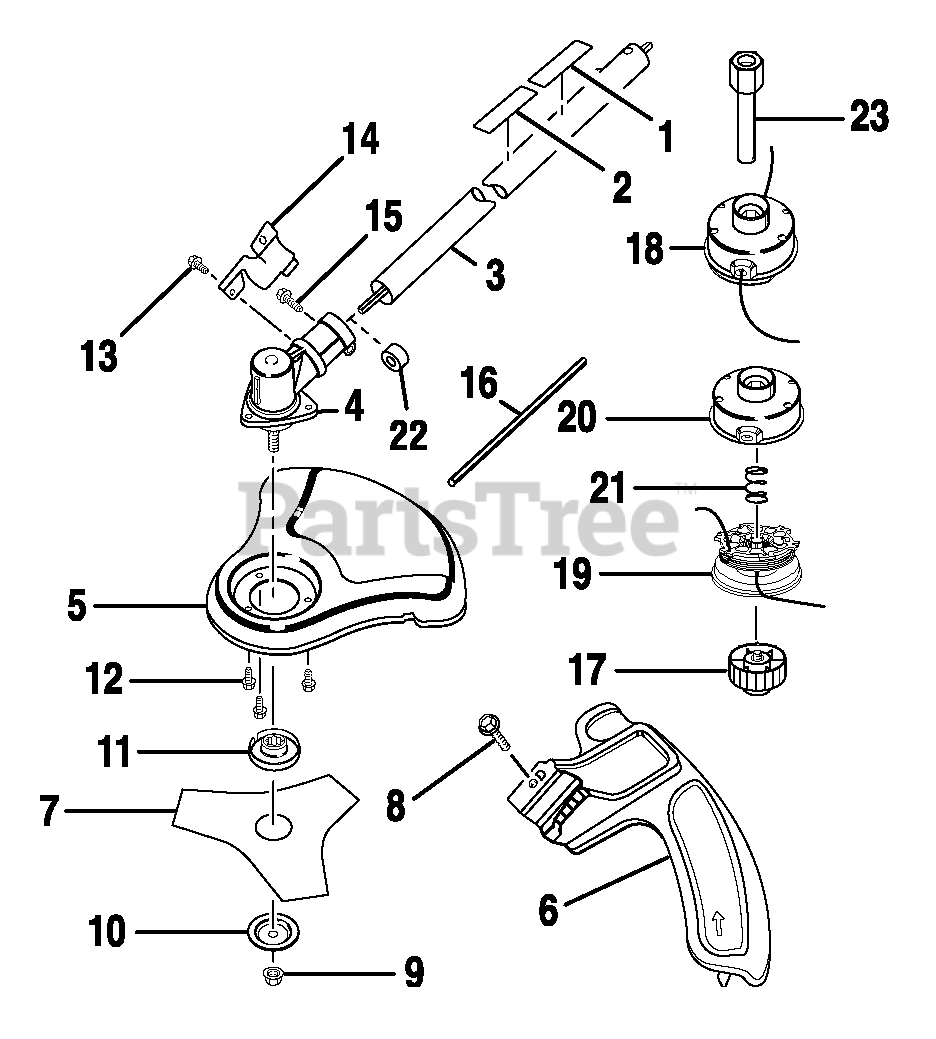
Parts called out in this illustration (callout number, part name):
1	Expand-it Label
2	Brushcutter Safety Label
3	Straight Shaft Assy.
4	Gear Head
5	Brushcutter Guard
6	Grass Deflector Assy.
7	Tri-Arc ® Blade
8	Screw (1/4-2- x 1-1/4 in.)
9	Lock Nut
10	Cupped Washer
11	Flanged Washer
12	Screw (10-24 x 1/2 in.)
13	Screw (10-24 x 5/8 in.)
15	Screw (1/4-20 x 1-1/4 in.)
16	Holding Pin
17	Spool Retainer (Red)
18	Complete String Head (.095 in.)
19	Spool and String (.095 in.) w/Spring
20	Housing and Eyelet
22	Spacer
23	Shaft Adapter
